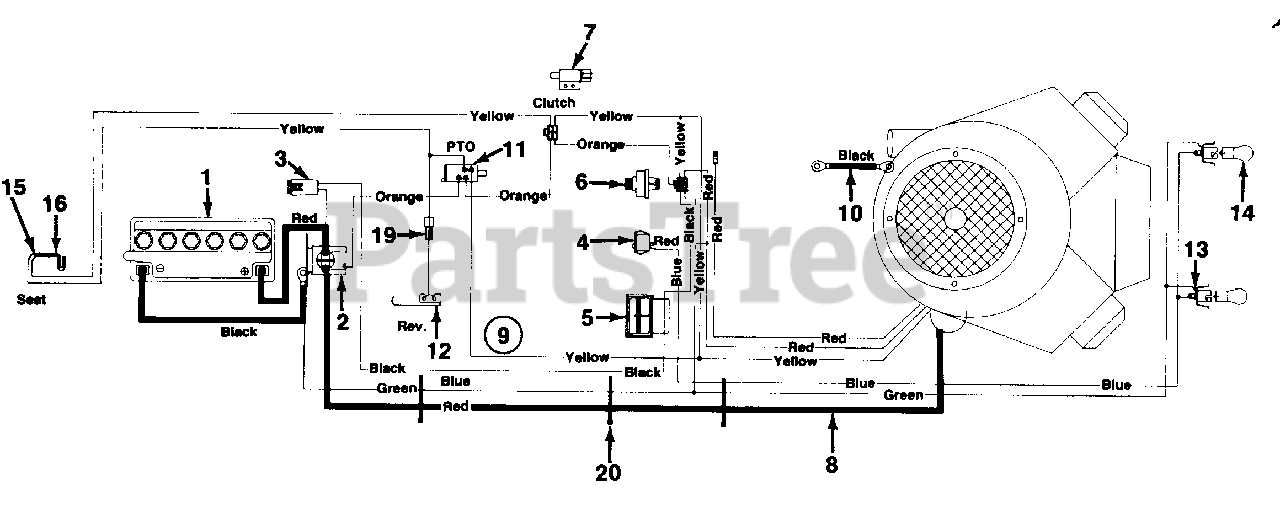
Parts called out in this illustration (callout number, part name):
1	Battery-1 2V
2	Solenoid
3	Fuse 20 Amps
4	Light Switch
5	Ammeter
6	Ignition Switch
7	Safety Switch
8	Electric Wire-30.0" Lg.
9	Wire Harness
10	Ground Wire-7.5" Lg.
11	Safety Switch
12	Safety Switch
13	Headlight Socket
14	Headlight Bulb
15	Safety Switch
16	Safety Switch
19	Ext. Wire
